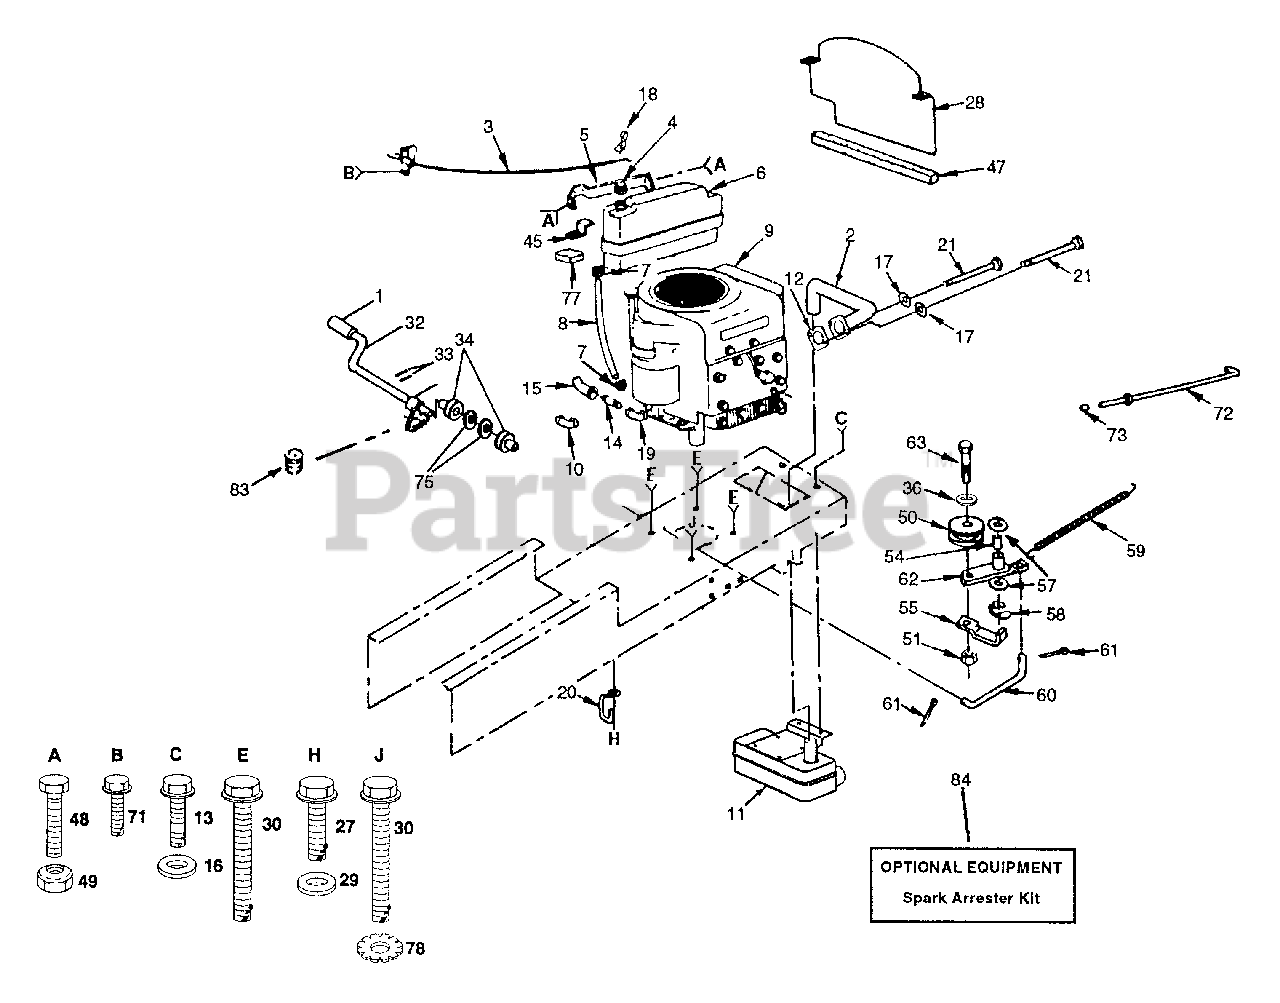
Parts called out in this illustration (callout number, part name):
1	Pedal Cover
2	Pipe, Exhaust 1800
3	Control, Throttle
4	Fuel Cap
5	Support, Tank, Fuel
6	Tank, Fuel
7	Hose Clamp
8	Fuel Line
9	Engine Briggs & Stratton
10	900 Street Elbow 3/8 NPT
12	Gasket, Exhaust
13	Screw, Thread Rolling 5/16-18 x 3/4
14	Nipple, Pipe 3/8-18 NPT x 3"
15	900 Elbow 3/8 NPT
16	Washer 11/32 x 1-1/4 x 16 Ga.
17	Washer, Lock Hvy. Helical Spring 5/16
18	Stop, Throttle
19	45° Street Elbow
20	Retainer, Belt, Chassis L.H.
21	Screw, Hex.Hd. Cap 5/16 - 18 x 5/8
27	Screw, Hex Washer Thd. Rolling 3/8-16 x 3/4
28	Baffle, Vertical
29	Washer 13/32 x 13/16 x 12 Ga.
30	Screw, Hex Washer Hd. Thread Rolling 3/8 - 16 x 1 - 1/4 Type TT
32	Shaft, Pedal, Foot
33	Roll Pin 3/16 x 1
34	Bearing, Nylon
36	Washer 13/32 x 13/16 x 16 Ga.
45	Brace, Tank
47	Strip, Foam
48	Bolt, Hex 5/16-18 x 3/4 Gr. 5
49	Locknut 5/16-18 Gr. B
50	Idler, V. Groove
51	Nut, Crownlock 3/8-16
55	Retainer, Belt
57	Washer, Hardened
58	Ring, Klip
59	Spring, Return Clutch
60	Link, Clutch
61	Pin, Cotter 1/8 x 3/4
62	Bellcrank Assembly
63	Bolt Hex 3/8 - 16 x 1-1/2
71	Screw Hex Washer Head Thread Cutting 1/4-20 x 1/2
72	Rod, Brake, Park
73	Plunger Cap
75	Washer 21/32 x 1 x 16 Ga.
77	Pad, Spacer
78	Washer, Lock 3/8 - Ext.Tooth
83	Oil Drain Plug
84	Spark Arrester Kit
